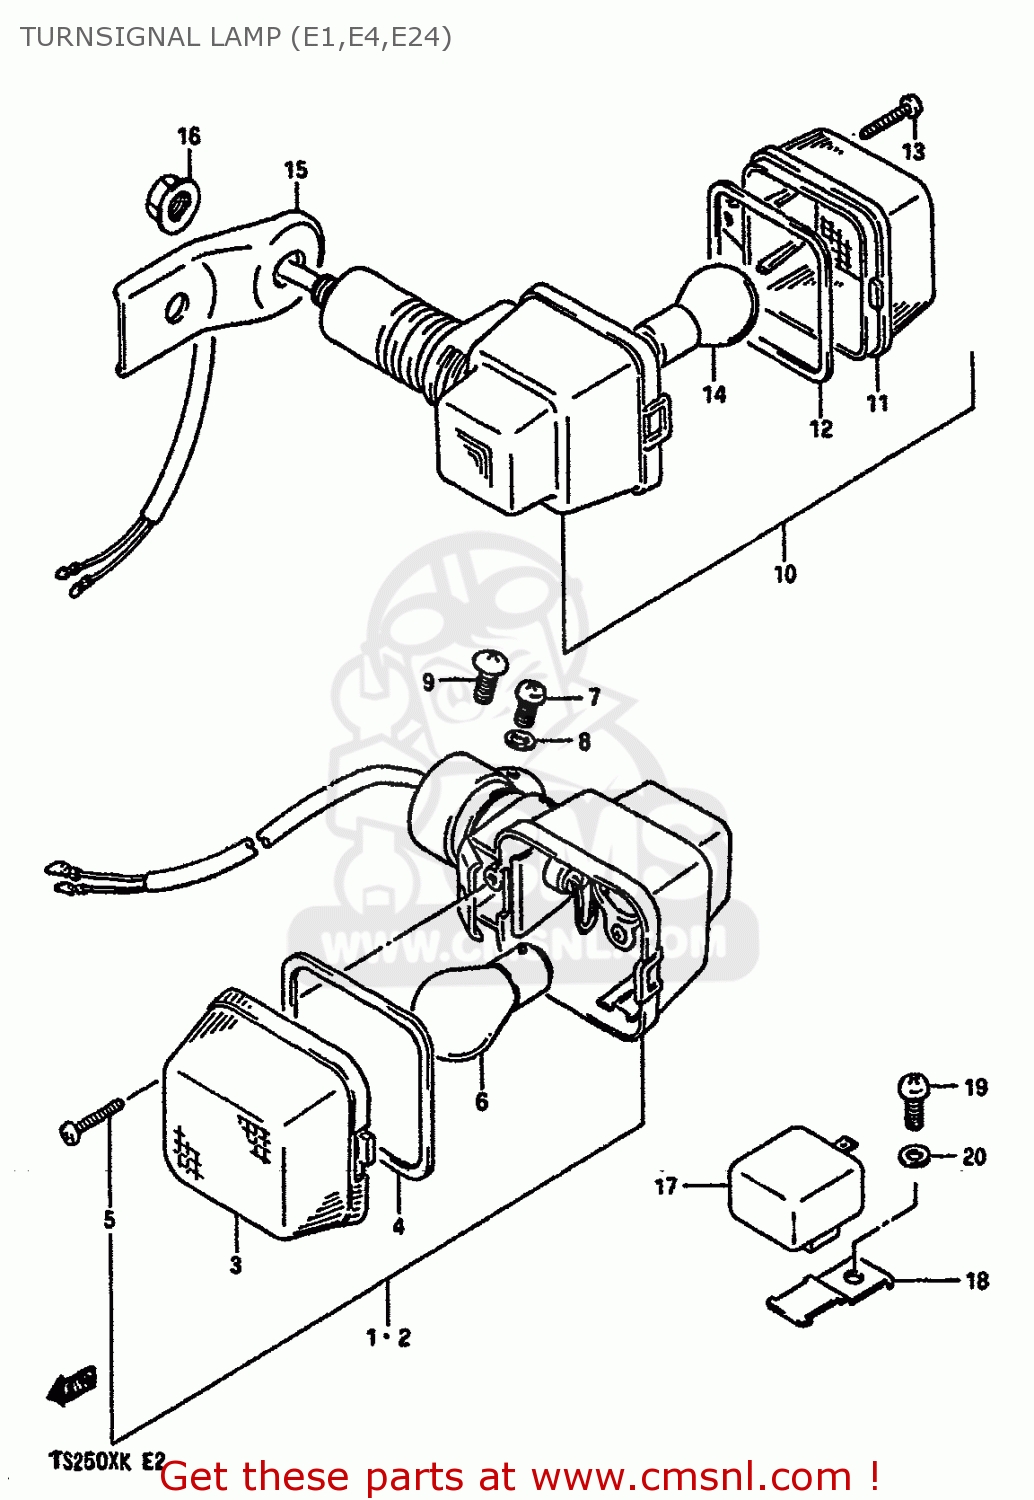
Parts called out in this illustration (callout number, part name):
1	LAMP ASSY,FR TURNSIGNAL RH
2	LAMP ASSY,FR TURNSIGNAL LH
3	LENS
4	GASKET (NAS)
5	SCREW
6	BULB 12V 21W
7	SCREW
8	WASHER,LOCK
9	SCREW, FRONT & REAR
10	LAMP ASSY,RR TURNSIGNAL
11	LENS
12	GASKET (NAS)
13	SCREW
14	BULB 12V 21W
15	BRACKET,RR TURNSIGNAL LAMP
16	NUT
17	RELAY ASSEMBLY,TURN SIGNAL
18	BRACKET,RELAY
19	SCREW
20	WASHER,LOCK
